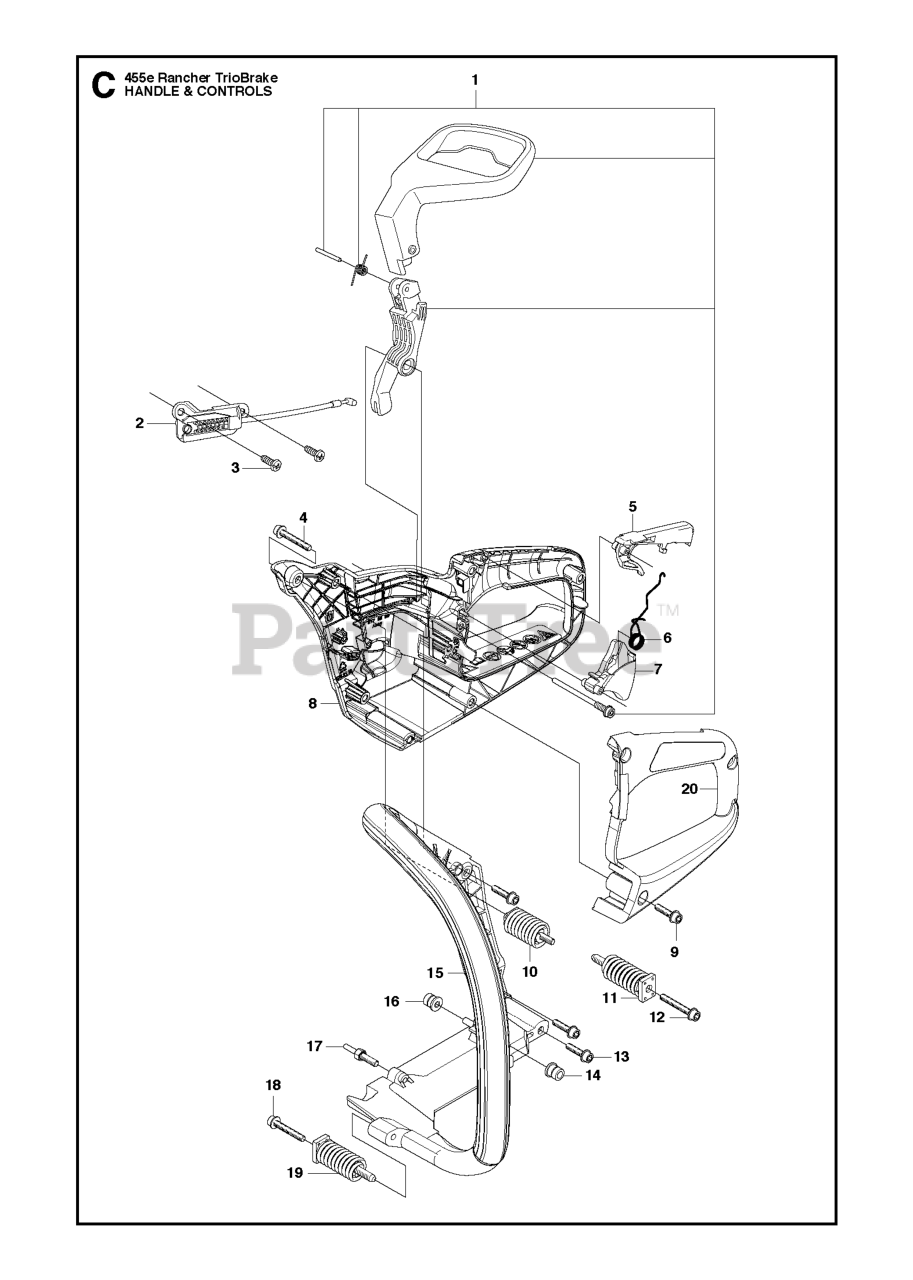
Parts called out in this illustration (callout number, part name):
4	%SCREW
5	THROTTLE LOCK
7	THROTTLE TRIGGER
8	REAR HANDLE
10	VIBRATIONS ABSORBER
11	VIBRATION ABSORBER
14	MOVEMENT LIMITER
15	FRONT HANDLE
16	MOVEMENT LIMITER
20	CAP - LEFT SIDE HANDLE
